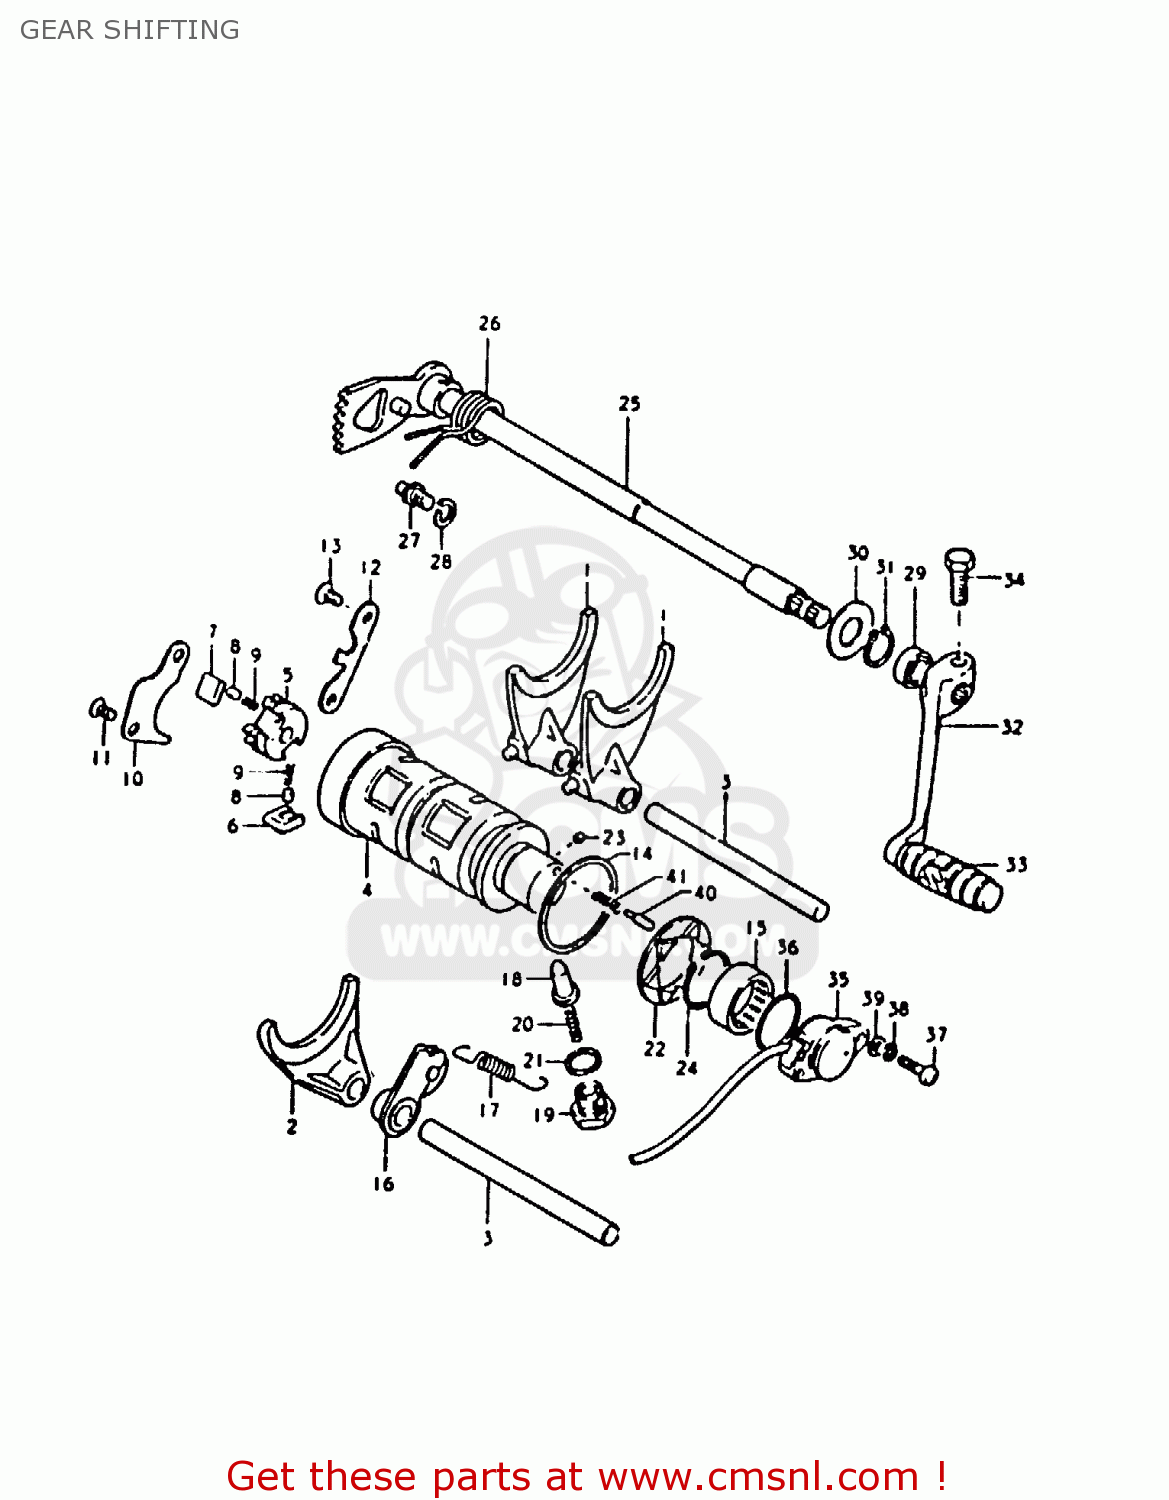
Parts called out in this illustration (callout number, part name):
1	FORK,GEAR SHIFT NO.1
2	FORK,GEAR SHIFT NO.3
3	SHAFT,GEAR SHIFT FORK
4	CAM,GEAR SHIFT
5	RETAINER,GEAR SHIFT CAM
6	PAWL,GEAR SHIFT NO.1
7	PAWL,GEAR SHIFT NO.2
8	PIN(5X8)
9	SPRING
10	LIFTER,GEAR SHIFT PAWL
11	SCREW
12	GUIDE,GEAR SHIFT CAM
13	SCREW
14	WASHER(40X45X1)
15	BEARING(25X32X12)
16	STOPPER,GEAR SHIFT CAM
17	SPRING
18	STOPPER,GEAR SHIFT CAM NO.2
19	HOLDER,GEAR SHIFT CAM STOP SPR
20	SPRING
21	GASKET(14X19.2X2) (NAS)
22	PLATE,GEAR SHIFT CAM STOPPER
23	PIN 4X6
24	CIRCLIP
25	SHAFT,GEAR SHIFT
26	SPRING
27	STOPPER,GEAR SHIFT CAM
28	WASHER
29	OIL SEAL
30	WASHER (12.5X27X1.6)
31	SPRING,RETAINER
32	LEVER ASSY,GEAR SHIFT
33	RUBBER,GEAR SHIFT PEDAL
34	BOLT
35	TERMINAL BASE,NEUTRAL SWITCH
36	O-RING (D:2.4 ID:26.2)
37	SCREW 5X20
38	LOCK WASHER
39	WASHER
40	PIN(5X15.5)
41	SPRING
